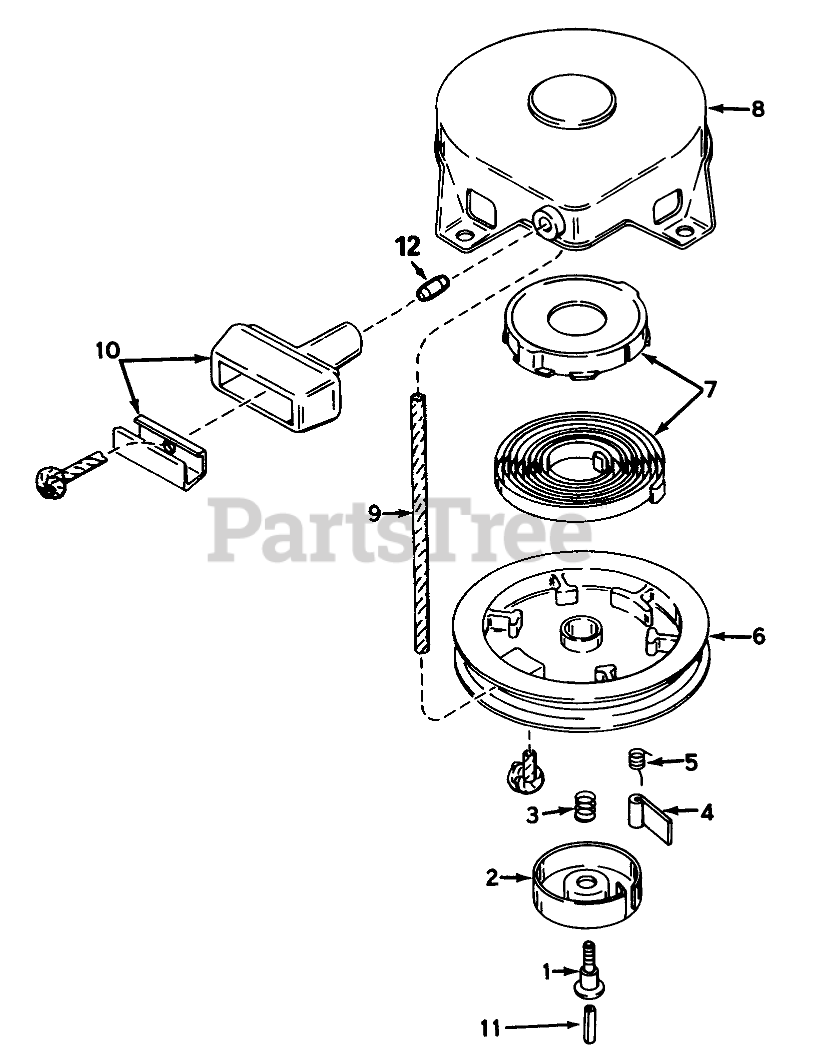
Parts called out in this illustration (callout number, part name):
2	Retainer
3	Spring-Brake
4	Dog-Starter
5	Spring-Dog
7	Spring & Keeper Assy
8	Housing Assy.-Starter (Incl. #1)
9	Rope-Starter (98 cut to length)
10	Assy., Starter
11	Centering
12	Retainer-Starter Rope
